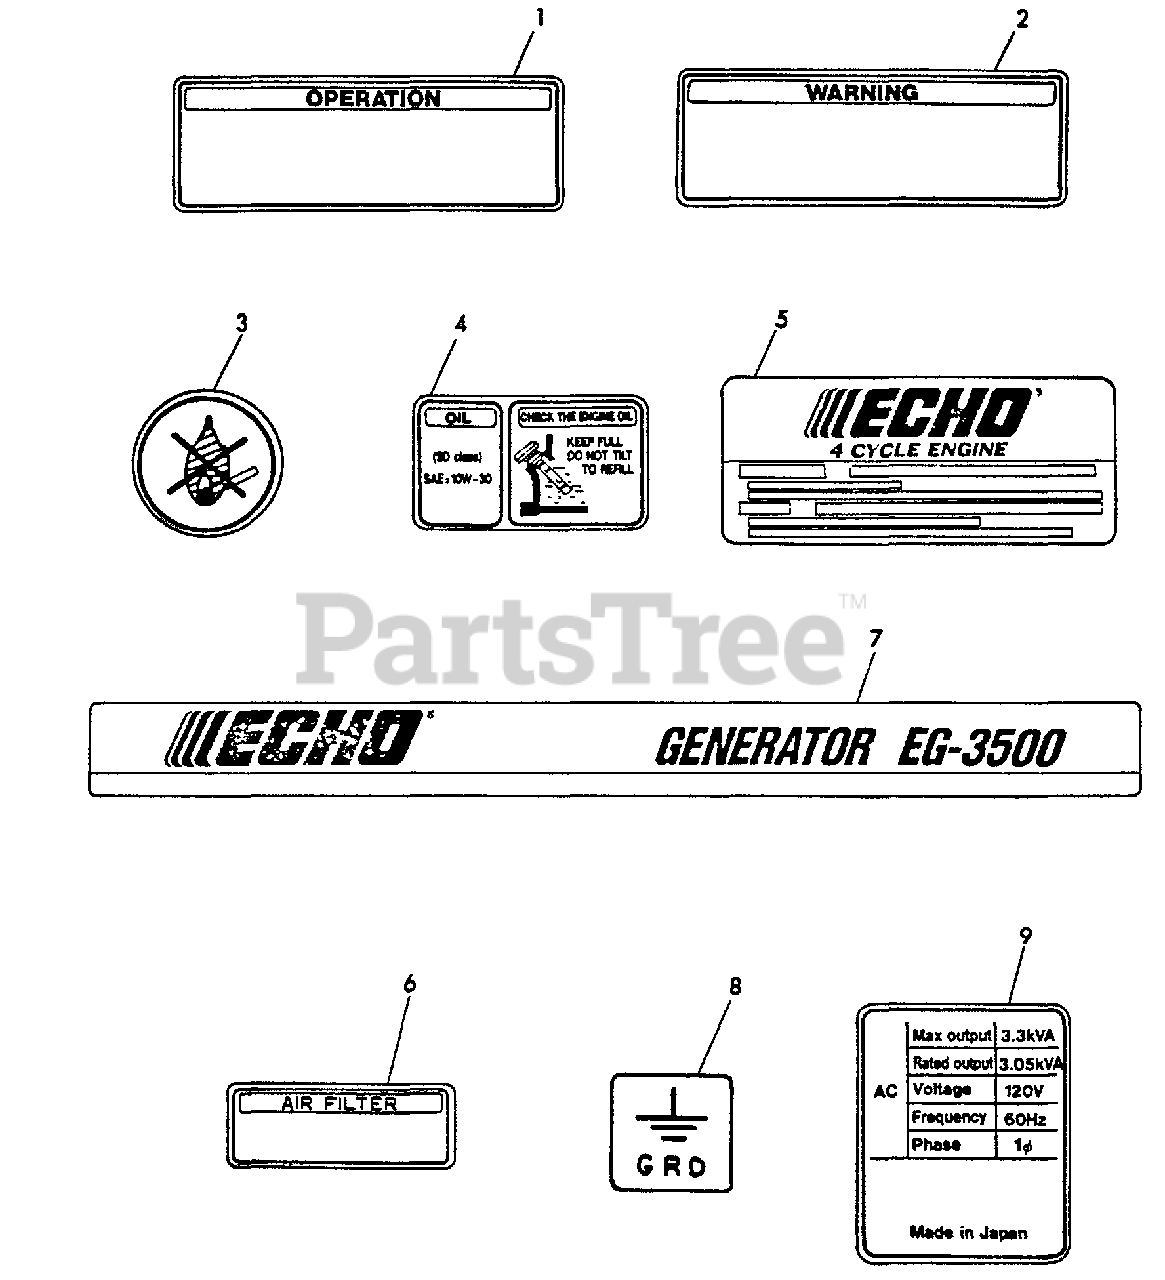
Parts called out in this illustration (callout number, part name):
1	LABEL - OPERATION
2	LABEL - WARNING
3	LABEL - NON FIRE
4	LABEL - OIL
5	LABEL - ECHO
6	LABEL - AIR CLEANER
7	LABEL - MODEL EG3500
8	LABEL - GROUND
9	LABEL - GENERATOR
